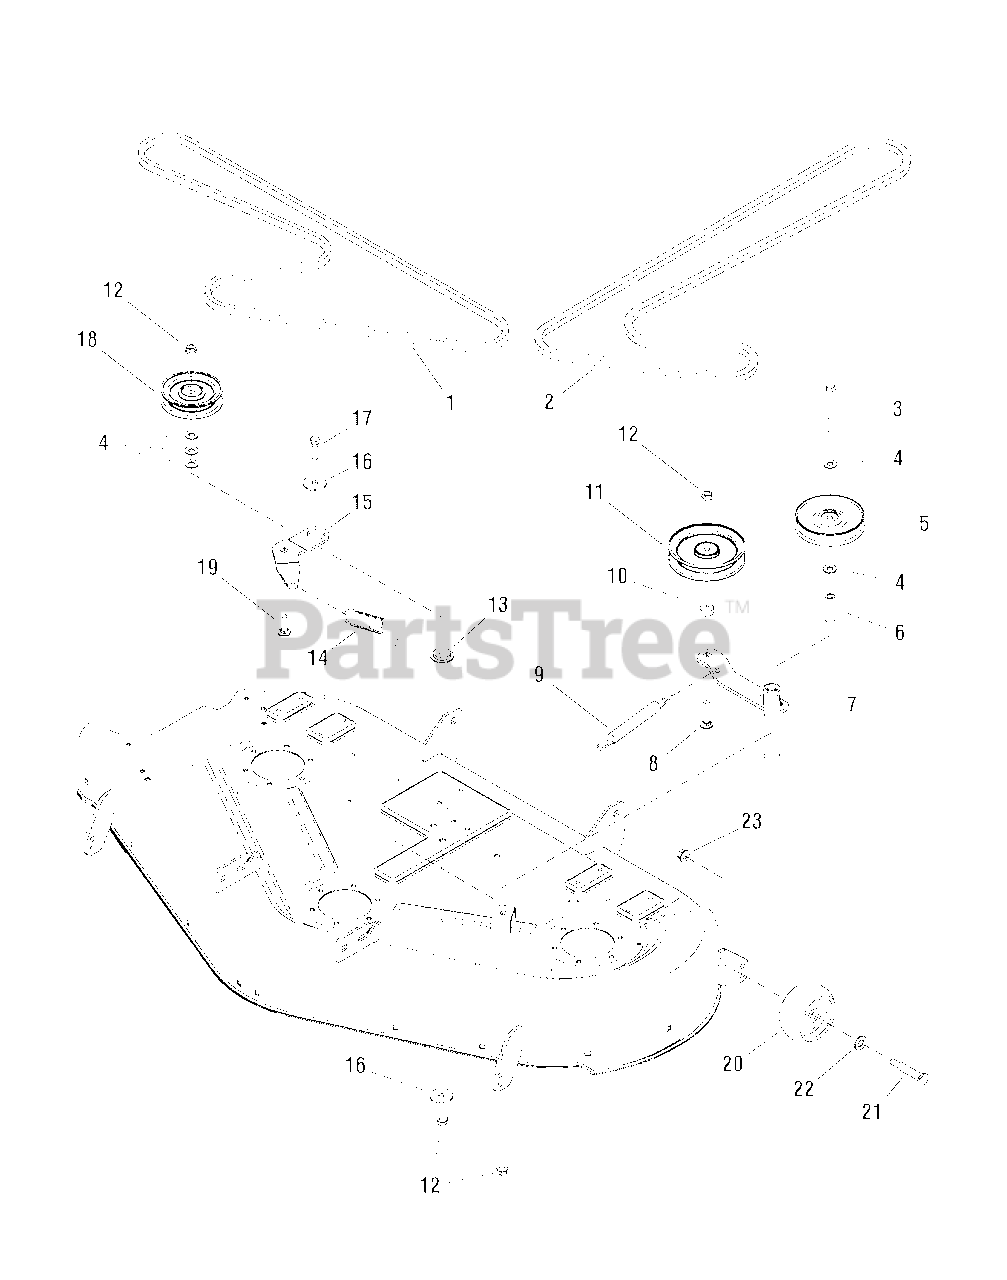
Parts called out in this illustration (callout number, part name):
1	V-BELT, Arbor Drive, 91.1 Kevlar
2	V-BELT, P.T.O. Drive, 73.24 A-Wedge
3	CAPSCREW, Hex Head, 3/8-16 x 3-1/4, G5
4	WASHER, Flat, 3/8
5	PULLEY, 4-1/2 OD 3/8 ID .63 Groove
7	ARM ASSEMBLY, Idler with Bushings
8	CARRIAGE BOLT, 3/8-16 x 1-3/4, G5
9	SPRING, Extension
10	SPACER, Powdered Metal
11	PULLEY, Idler Flat
12	NUT, Hex Flange Lock, 3/8-16
13	SPACER, Idler Powdered Metal
14	SPRING, Extension
15	ARM, Idler
16	WASHER, Flat, 3/8
17	CAPSCREW, Hex Head, 3/8-16 x 1-1/4, G5
18	PULLEY, Idler
19	CARRIAGE BOLT, 3/8-16 x 1-1/4, G5
20	GAUGE WHEEL
21	BOLT, Wheel, 3/8-16 x 2.781
22	WASHER, Flat, 1/2
23	NUT, Hex Flange, 3/8-16 ESNA
